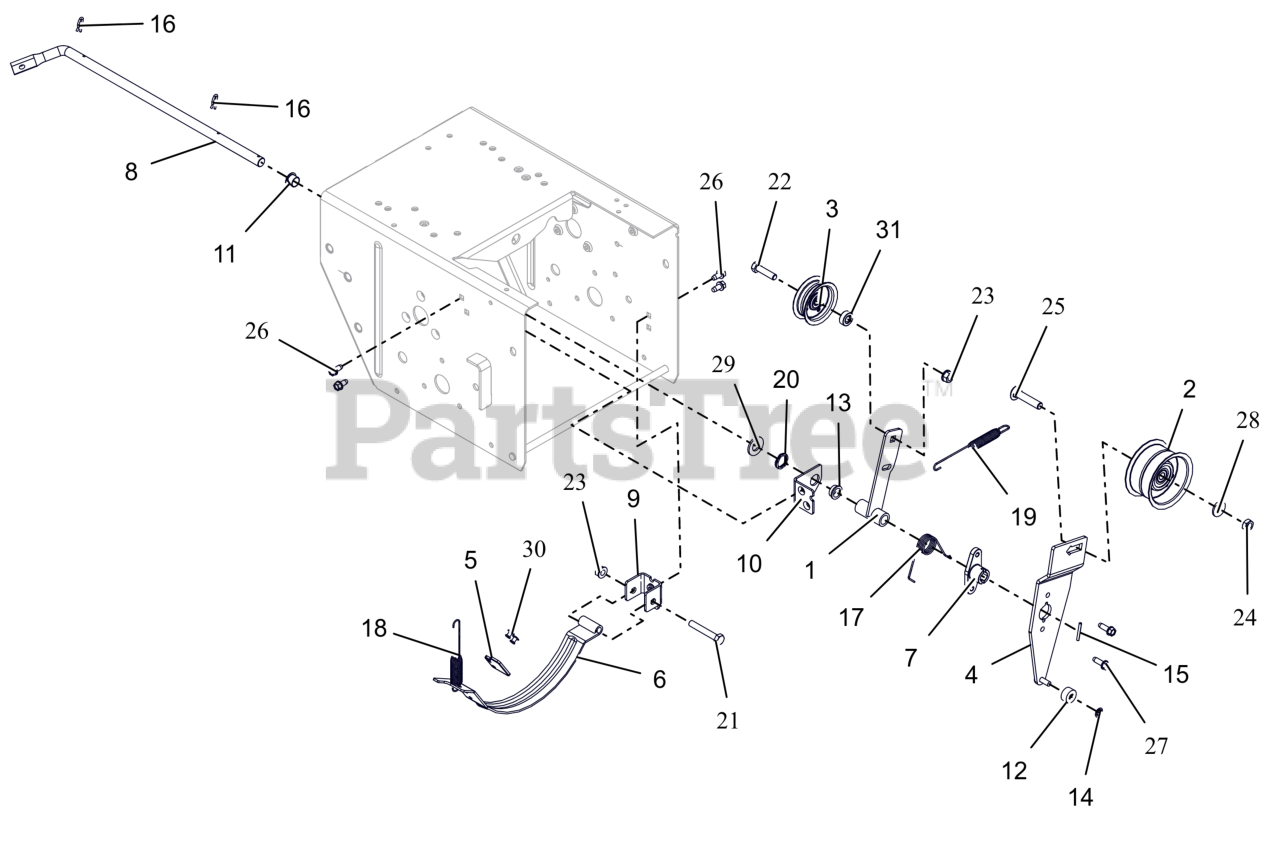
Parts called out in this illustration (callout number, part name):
1	ARM, IDLER-TRACTION
2	IDLER, FLANGE -2.75 OD X .375 ID
3	IDLER, FLAT - 2.00"
4	ARM, IDLER - ATTACHMENT
5	PAD, BRAKE
6	ARM, BRAKE-ATTACHMENT
7	HUB, BRAKE ARM
8	ARM, ATTACHMENT
9	PIVOT, BRAKE
10	BRACKET, SUPPORT
11	BUSHING, POLYLINER-.50 SPLIT
12	BSHG,SLV .265 X .625 X .375
13	BSHG,FLANGE .500X.625X.270X.75
14	RG-RTNG-EXT .250X.010
15	PIN-ROLL .125X1.00
16	CLIP, SPRING
17	SG-TORS .067X.88
18	SG-TENS .056X.60X4.40
19	SG-TENS .06X.482X5.35
20	WAVE SPRING .600X.875X.25FH
21	BLT, HEX .31-18X2.00 G5 ZCC
22	BLT, HEX .31-18X1.25 G5 ZCC
23	NUT-LK-TOP-FLG .312-18 GF ZCC
24	NUT-LK-CTR-JAM .375-16 GB ZCC
25	BLT, RHSSN .38-16X1.75 G5 ZCC
26	SCR-TAP .25-20X.50 HWH ZCC
27	SCR,TAP .25-20X.75 HWH TR ZCC
28	WSHR,FLT .375X.875X.083 ZCC
29	WSHR,FLT .531X1.062X.095 ZCC
30	RVT, POP .1875 ZCC
31	SPCR, BRG .315X.500X.358X.281
